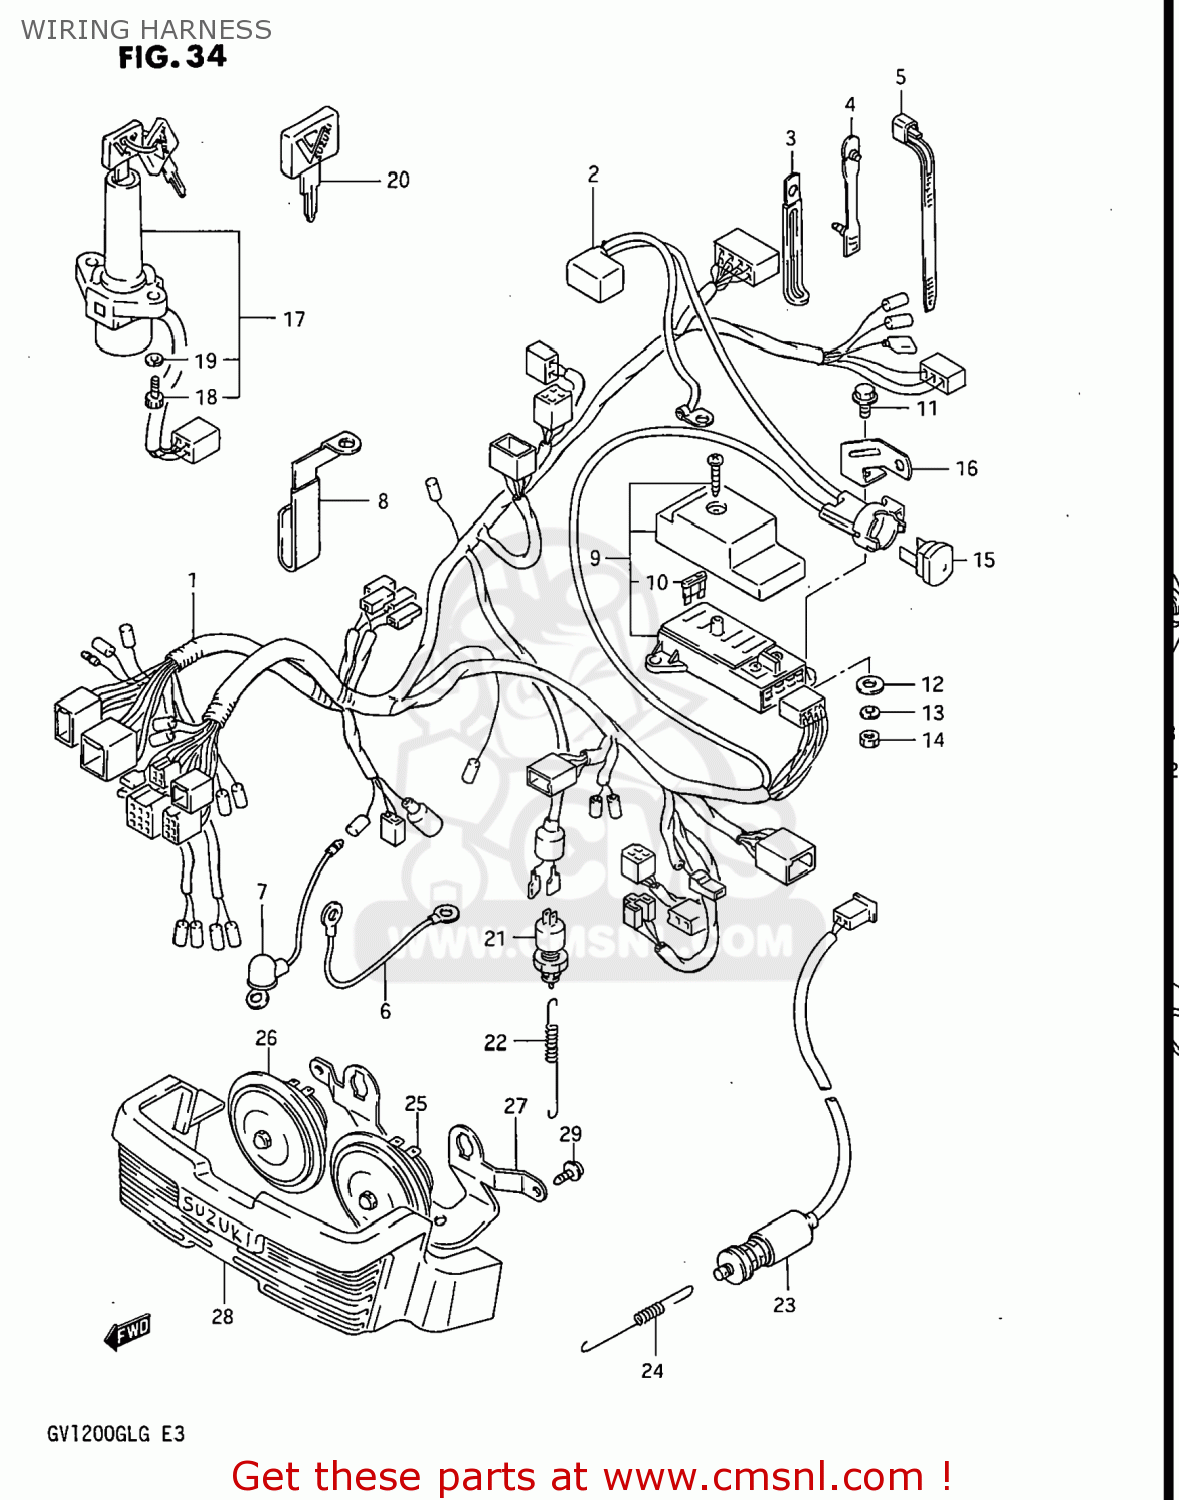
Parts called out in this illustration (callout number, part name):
1	HARNESS,WIRING
2	CAP,BATTERY PLUS TERMINAL
3	CLAMP
4	CLAMP,L:88
5	CLAMP(L:95)
6	WIRE
7	WIRE
8	CLAMP,WIRING HARNESS
9	BOX ASSEMBLY,FUSE
10	FUSE(10A)
11	BOLT
12	WASHER
13	WASHER,LOCK
14	NUT
15	BREAKER ASSY,CIRCUT
16	BRACKET
17	SWITCH ASSEMBLY,IGNITION
18	BOLT
19	WASHER,LOCK
20	KEY,BLANK
21	SWITCH ASSEMBLY,STOP LAMP
22	SPRING
23	SWITCH ASSEMBLY,SIDE STAND
24	SPRING
25	HORN ASSEMBLY,HIGH PITCH
26	HORN ASSEMBLY,LOW PITCH
27	BRACKET,HORN
28	COVER,HORN
29	SCREW
